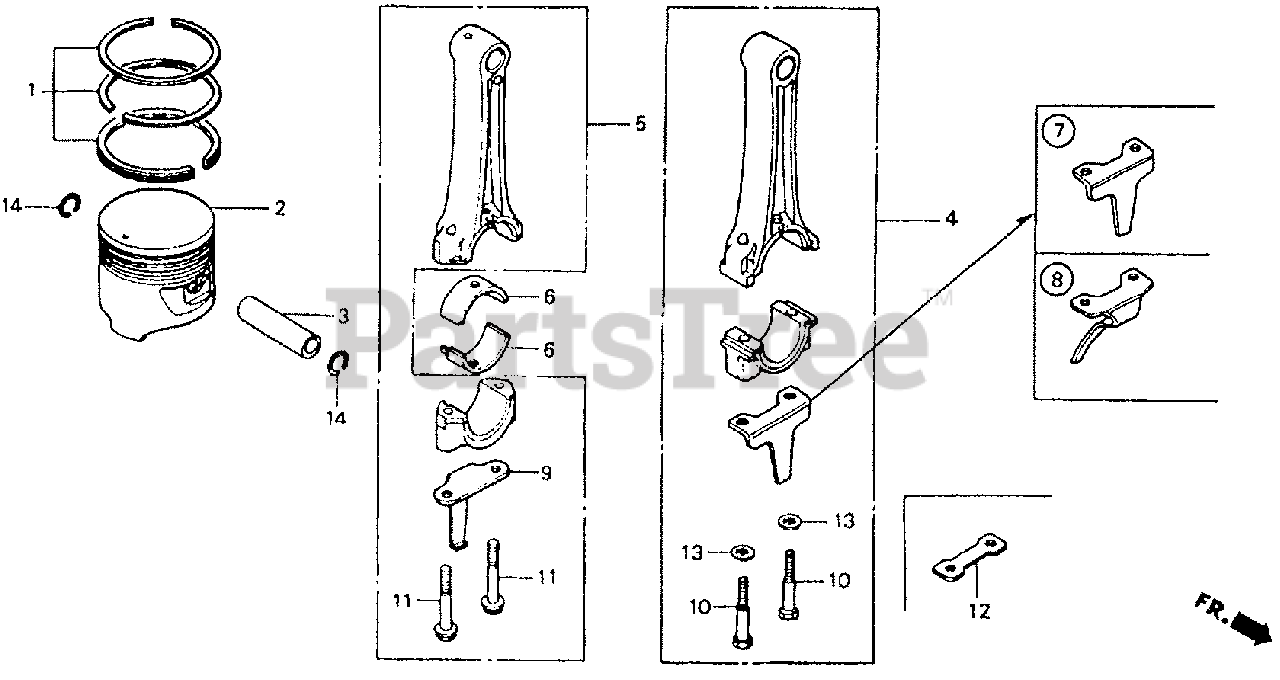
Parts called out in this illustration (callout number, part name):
1	RING SET, PISTON (STD)
1	RING SET, PISTON (STD) (NOT AVAILABLE)
1	RING SET, PISTON (OS 0.25)
1	RING, PISTON (OS 0.50)
1	RING SET, PISTON (OS 0.50) (NOT AVAILABLE)
1	RING SET, PISTON (0.75) (NOT AVAILABLE)
2	PISTON (STD)
2	PISTON (OS 0.25)
2	PISTON (OS 0.50)
2	PISTON (0.75)
3	PIN, PISTON
4	ROD ASSY., CONNECTING
4	ROD ASSY., CONNECTING (NOT AVAILABLE)
4	ROD ASSY., CONNECTING (UNDER SIZE)
4	ROD ASSY., CONNECTING (UNDER SIZE) (NOT AVAILABLE)
5	ROD ASSY., CONNECTING
6	BEARING A, CONNECTING ROD (BLACK)
6	BEARING B, CONNECTING ROD (BROWN)
6	BEARING C, CONNECTING ROD (GREEN)
6	BEARING D, CONNECTING ROD (YELLOW)
6	BEARING E, CONNECTING ROD (PINK)
7	DIPPER, CONNECTING ROD
7	DIPPER, CONNECTING ROD (NOT AVAILABLE)
8	DIPPER, CONNECTING ROD (NOT AVAILABLE)
9	DIPPER, CONNECTING ROD
10	BOLT, CONNECTING ROD (8MM) (NOT AVAILABLE)
11	BOLT, CONNECTING ROD (8MM)
12	WASHER, CONNECTING ROD
13	WASHER, LOCK (8MM)
14	CLIP, PISTON PIN (19MM)
